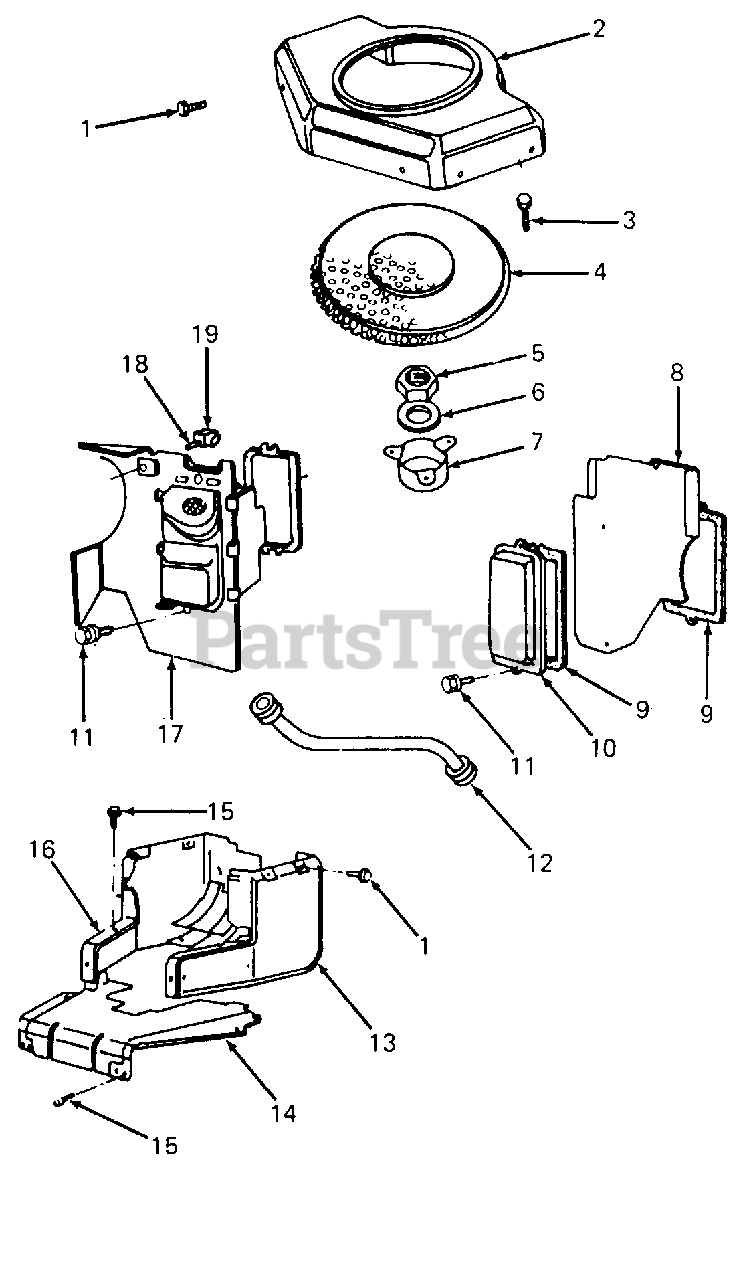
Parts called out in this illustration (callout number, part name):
1	Screw, Sem
2	Housing, Blower
3	Screw, Sem
4	Screen, Flush Rotating
6	Washer, Spring
7	Cup, Screen Mtg
8	Baffle, Air, Cylinder #2
9	Gasket
10	Cover, Breather, Cylinder #2
11	Screw, Sem
12	Tube, Breather
13	Cover Assy, Air Guide, Cylinder #2
14	Top Plate Assy
15	Screw, Sem
16	Cover Assy, Air Guide, Cylinder #1
17	Breather Assy #1
19	Grommet, Insulator
